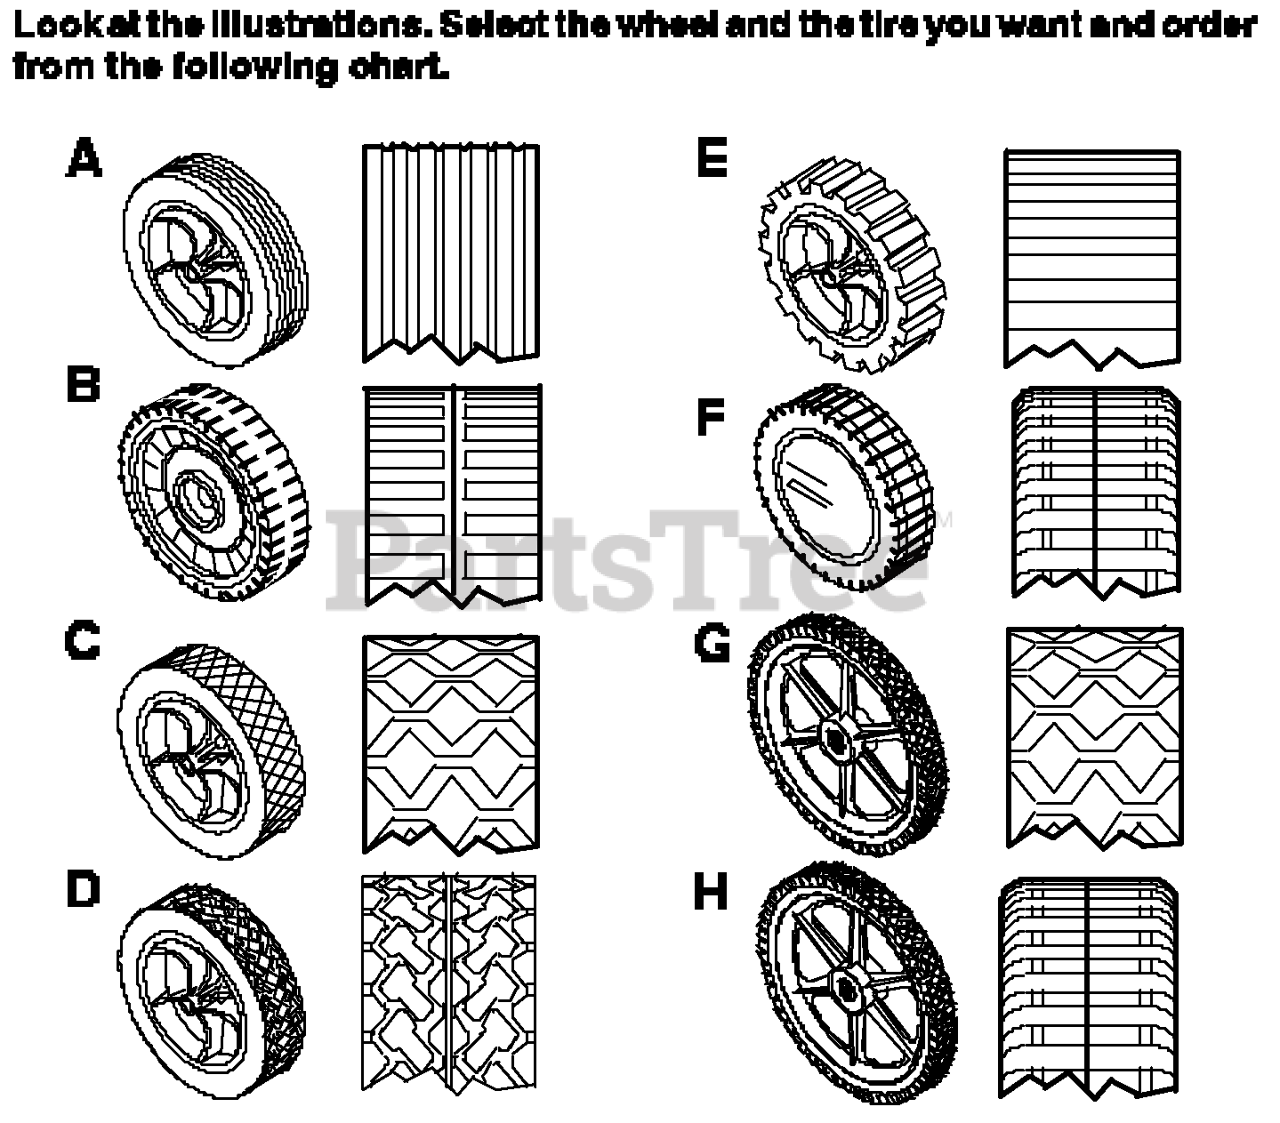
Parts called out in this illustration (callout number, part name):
A	WHEEL & TIRE ASSEMBLY, Light Gray, 8"
A	8-inch Plastic, Dark Gray
A	8-inch Metal, White
B	7-inch Plastic, White
B	7-inch Plastic, Light Gray
B	7-inch Plastic, Dark Gray
C	6-inch Plastic, White
C	7-inch Plastic, White
C	7-inch Plastic, Light Gray
C	7-inch Plastic, Dark Gray
C	8-inch Plastic, White
C	8-inch Plastic, Light Gray
C	8-inch Plastic, Dark Gray
C	8-inch Metal, White
D	7-inch Plastic, White
D	WHEEL & TIRE ASSEMBLY, White, 8"
D	8-inch Plastic, Light Gray
D	8-inch Plastic, Dark Gray
E	WHEEL & TIRE ASSEMBLY, White, 8"
E	8-inch Plastic, Dark Gray
E	8-inch Metal, White
F	WHEEL & TIRE ASSEMBLY, White, 8"
F	8-inch Plastic, Light Gray
F	8-inch Plastic, Dark Gray
F	8-inch Ball Bearing, Light Gray
F	8-inch Ball Bearing, Dark Gray
G	14-inch, White
G	14-inch, Light Gray
G	14-inch, Dark Gray
G	WHEEL & TIRE ASSEMBLY, White, 14"
G	14-in, Ball Bearing, Light Gray
G	14-in, Ball Bearing, Dark Gray
H	14-inch, White
H	14-inch, Light Gray
H	14-inch, Dark Gray
H	WHEEL & TIRE ASSEMBLY, Ball Bearing, 14"
H	14-in, Ball Bearing, Light Gray
H	14-in, Ball Bearing, Dark Gray
